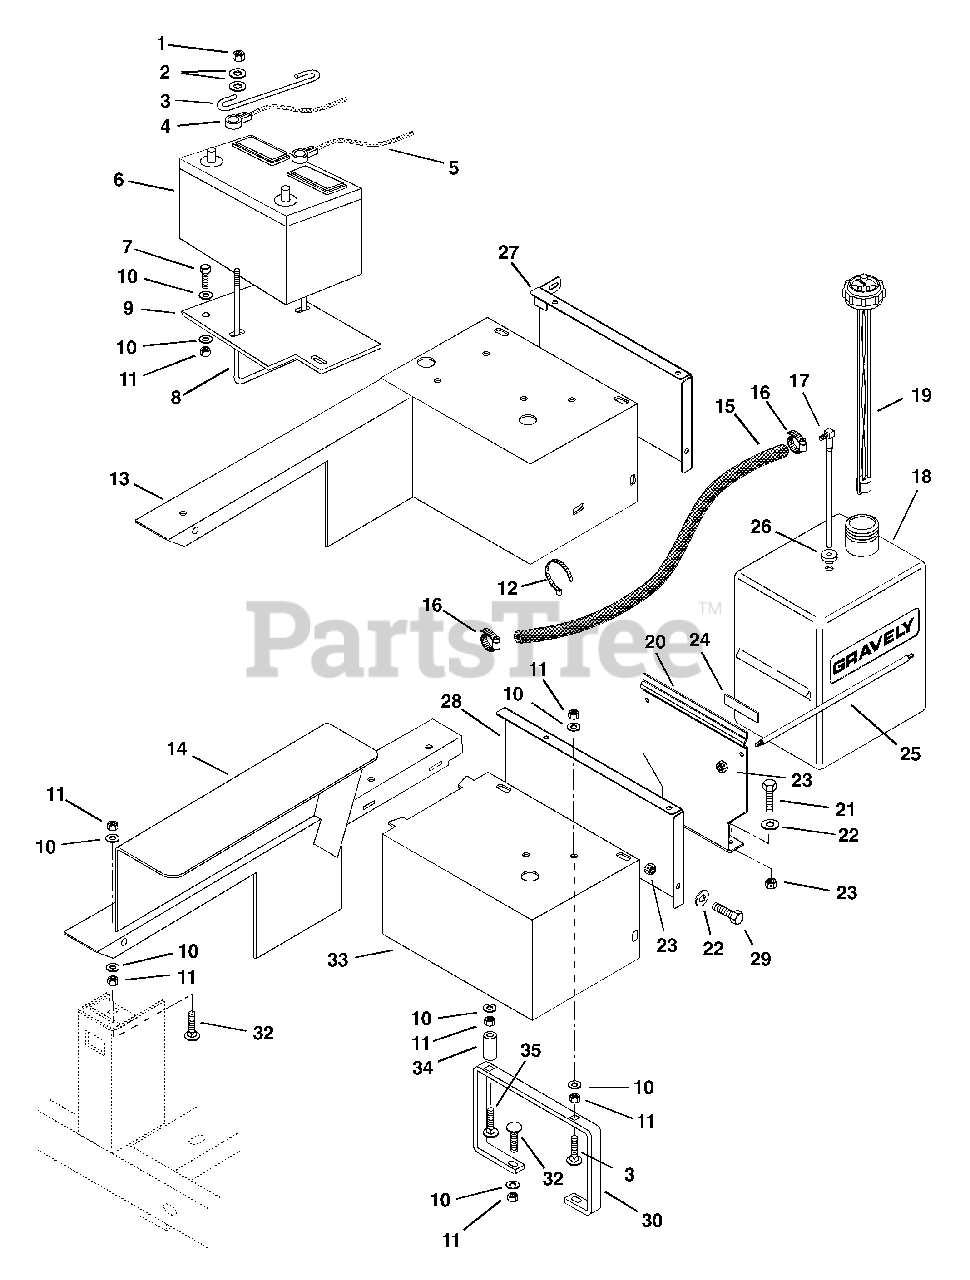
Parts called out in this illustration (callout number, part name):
1	Nut-Locking-Center .25-20
2	Washer-Flat-Steel .312 x .734 x .065
3	Rod, Hold Down
4	Battery Cable
5	Ground Cable
6	Battery
7	Bolt-Hex .38-16 x 1.00 Grade 5
8	Rod, Battery
9	Mounting Plate
10	Washer-Flat-Steel .438 x 1.00 x .083
11	Nut-Locking-Center .38-16
12	Tie Wrap
13	Guard, Belt Weldment
14	Guard-Belt Weldment
15	Gas Line-Bulk .25 ID
16	Hose Clamp
17	Fitting, Tank
18	Tank, Fuel
19	Gauge, Fuel
20	Tank Bracket
21	Bolt-Hex .31-18 x 1.00 Grade 5
22	Washer-Flat-Steel .38 x .875 x .083
23	Nut-Locking-Center .31-18
25	Rod, Tank
26	Bushing
27	Plate, End
28	Plate, End
29	Bolt-Hex .31-18 x .75 Grade 5
30	Stand-Belt Guard
31	Bolt-Round Head Square Neck .38-16 x 1.00 Grade 5
32	Bolt-Round Head Square Neck .38-16 x 1.25 Grade 5
33	Cover, Shaft
34	Spacer .493 x .675 x 2.00
35	Bolt-Round Head Square Neck .38-16 x 1.25 Grade 5
35	Bolt-Hex .38-16 x 3.25 Grade 5
